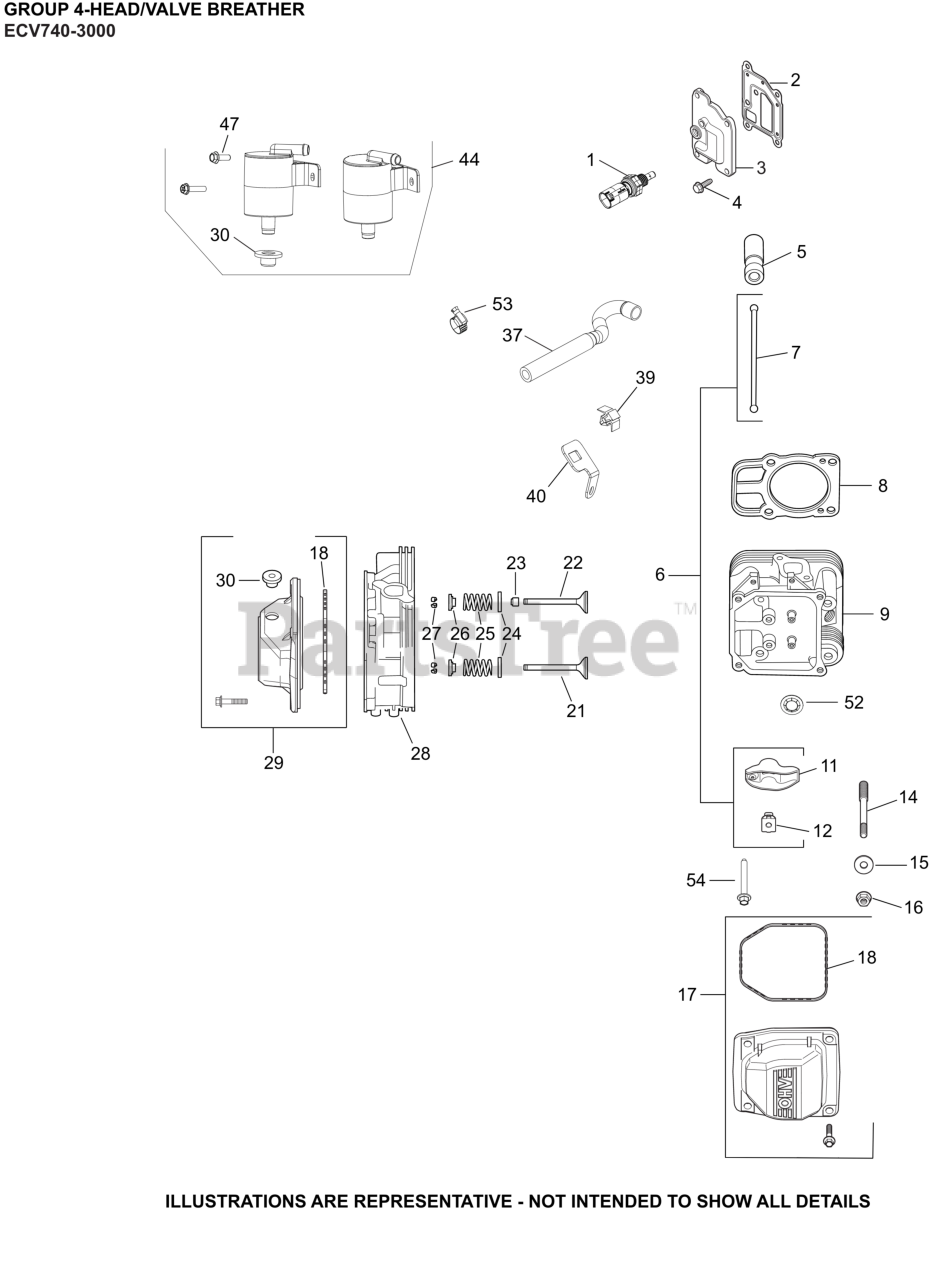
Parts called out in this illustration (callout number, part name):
1	SENSOR, TEMPERATURE
2	GASKET, BREATHER
3	KIT, BREATHER COVER
4	SCREW, THREAD FORMING
5	LIFTER, VALVE HYDRAULIC-USE 25 351 11-S
6	KIT, VALVE TRAIN
7	ROD, PUSH
8	KIT, GASKET CYLINDER HEAD
9	KIT, CYLINDER HEAD (#2)-(#2481804S)
11	ARM, ROCKER
12	PIVOT, ROCKER ARM
14	STUD, M8X1.25
15	WASHER, FLAT 8.6 MM
16	NUT, FLG M8X1.25
17	KIT, VALVE COVER-PLAIN (PLASTIC)
18	O-RING (YELLOW), VALVE CO
21	VALVE, EXHAUST
21	VALVE, EXHAUST (.25)
22	VALVE, INTAKE (STD)
22	VALVE, INTAKE (.25)-(#DSC)
23	SEAL, VALVE BAND
24	RETAINER, SPRING
25	SPRING, VALVE
26	KIT, RETAINER
27	CAP, VALVE SPRING
28	KIT, CYLINDER HEAD (#1)-(#2481803S)
29	KIT, VALVE COVER
30	GROMMET, RUBBER
37	HOSE, BREATHER
39	CLIP, O2 SENSOR
40	BRACKET, OXYGEN SENSOR
44	KIT, BREATHER SEPARATOR
47	SCREW, HI-LOW
52	RETAINER, VALVE GUIDE (KM)
54	SCREW, HEX FLANGE
NI	SCREW, HEX FLANGE (M6 X 31.625 DOG PT)
